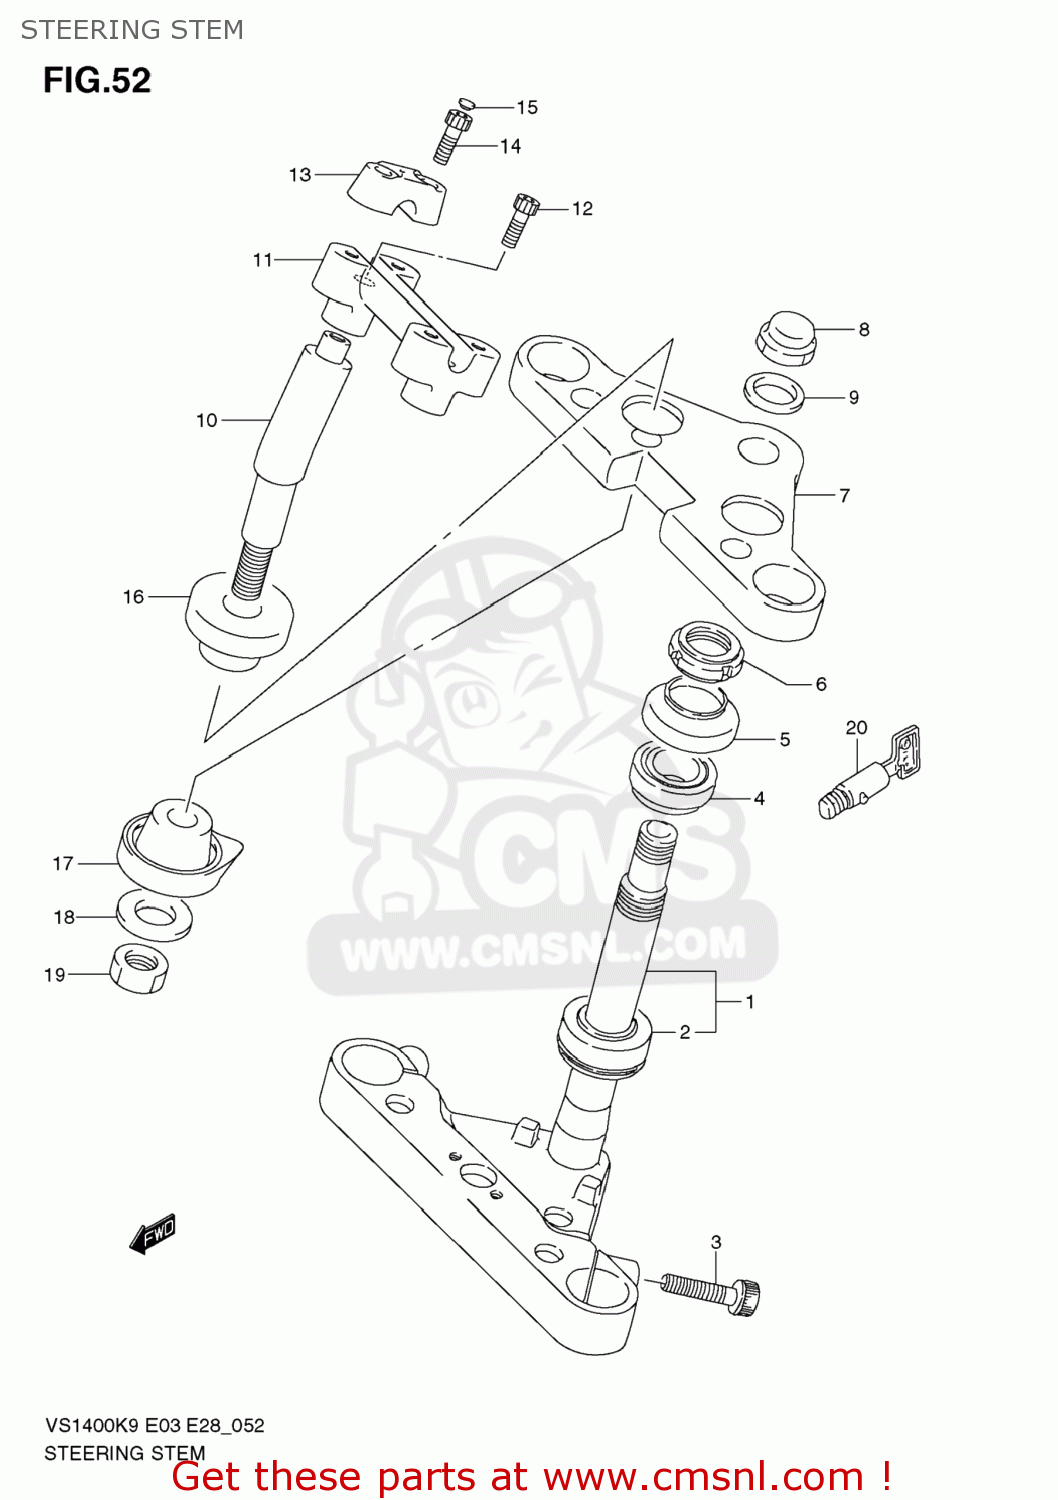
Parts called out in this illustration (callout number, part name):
1	STEM,STEERING
2	BEARING(30X55X17)
3	BOLT
4	BEARING(25X47X15)
5	SEAL,STEERING UPR DUST
6	NUT,STEERING STEM(25X44X10)
7	BRACKET,FR FORK UPR
8	NUT,CAP
9	WASHER(22.5X32X1.6)
10	STAY,HANDLE
11	HOLDER,HANDLE LWR
12	BOLT
13	HOLDER,HANDLE UPR
14	BOLT
15	CAP(OD:14.5)
16	DAMPER,RUBBER
17	CUSHION,RUBBER UNDER
18	WASHER
19	NUT
20	LOCK SET,STEERING
